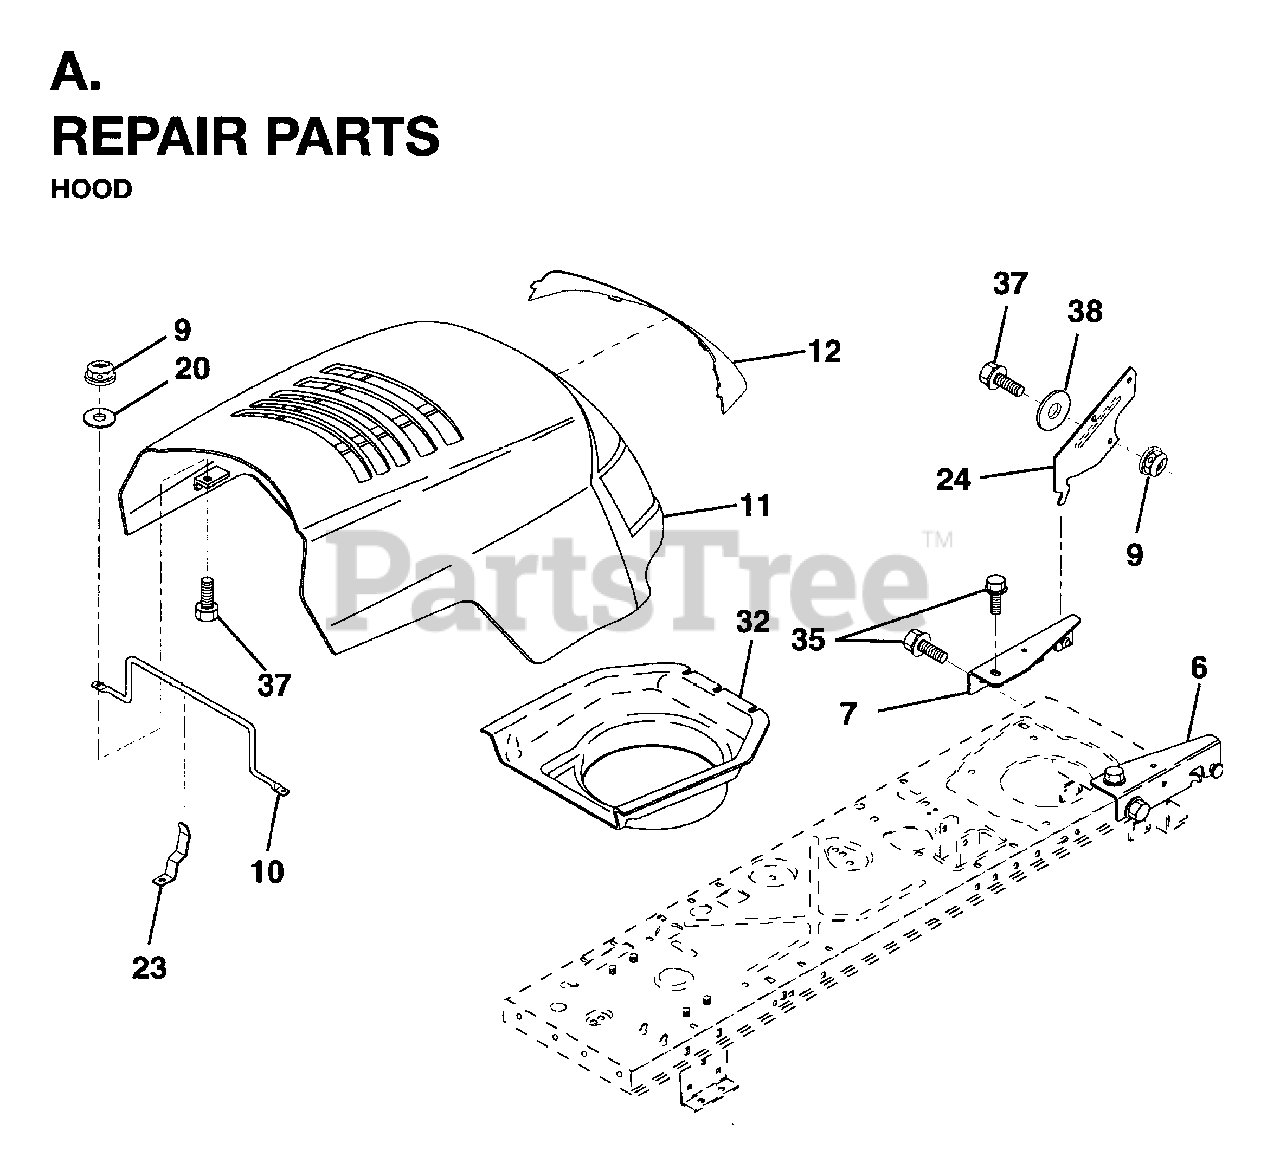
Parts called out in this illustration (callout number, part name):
6	BRACKET ASSY HOOD
7	BRACKET ASSY
9	NUT.CROWNLOCK.1/4
23	HOOD LATCH
35	BOLT
